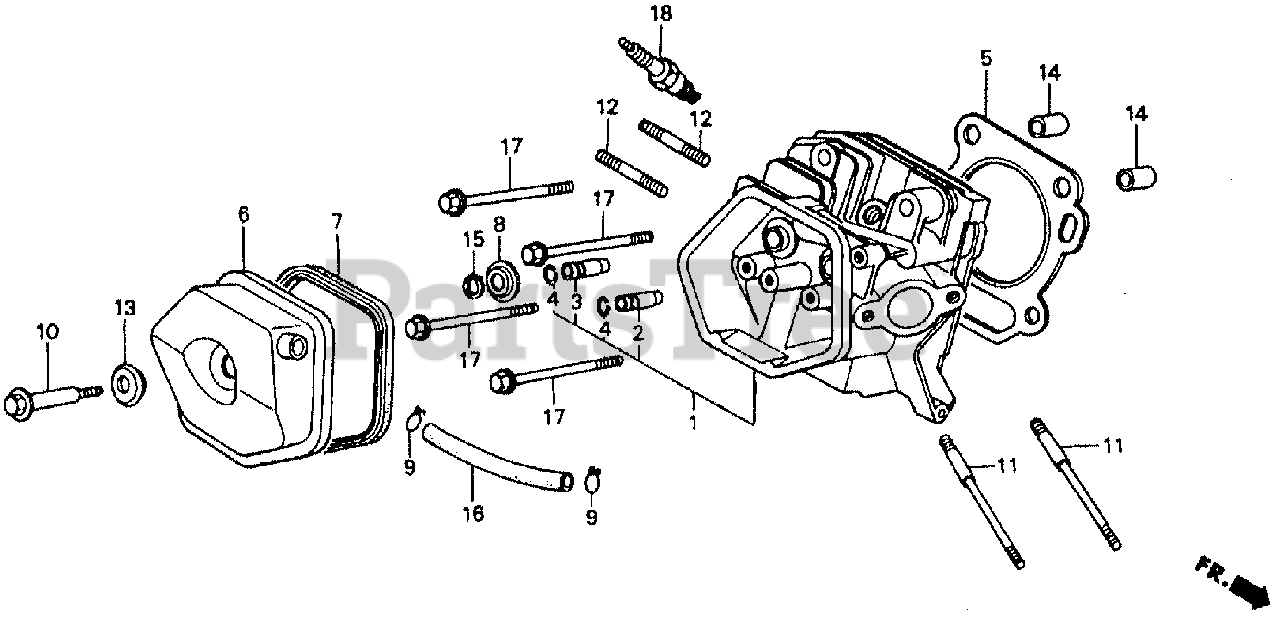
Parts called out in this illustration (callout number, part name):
1	CYLINDER HEAD
2	GUIDE, VALVE (OS)
3	GUIDE, EX. VALVE (OS)
4	CLIP, VALVE GUIDE
5	GASKET, CYLINDER HEAD
6	COVER KIT, HEAD
6	COVER, HEAD (Honda Code 2025401). (NOT AVAILABLE)
7	GASKET, CYLINDER HEAD COVER
8	SEAT, VALVE SPRING
10	BOLT, HEAD COVER
11	BOLT, STUD (8X123)
12	BOLT, STUD
12	BOLT 2, STUD (8X32)
13	WASHER, HEAD COVER
14	PIN A, DOWEL (12X20)
15	CIRCLIP (OUTER) (11MM)
16	BULK HOSE, VACUUM (11X1000) (Honda Code 4537312). (11X105)
16	BULK HOSE, VACUUM (8X1000) (Honda Code 5339163). (8X100)
17	BOLT, FLANGE (10X80)
18	SPARK PLUG (W16EPR-U) (DENSO)
18	SPARK PLUG (BPR6ES) (NGK)
18	SPARK PLUG (W20EPR-U) (DENSO)
